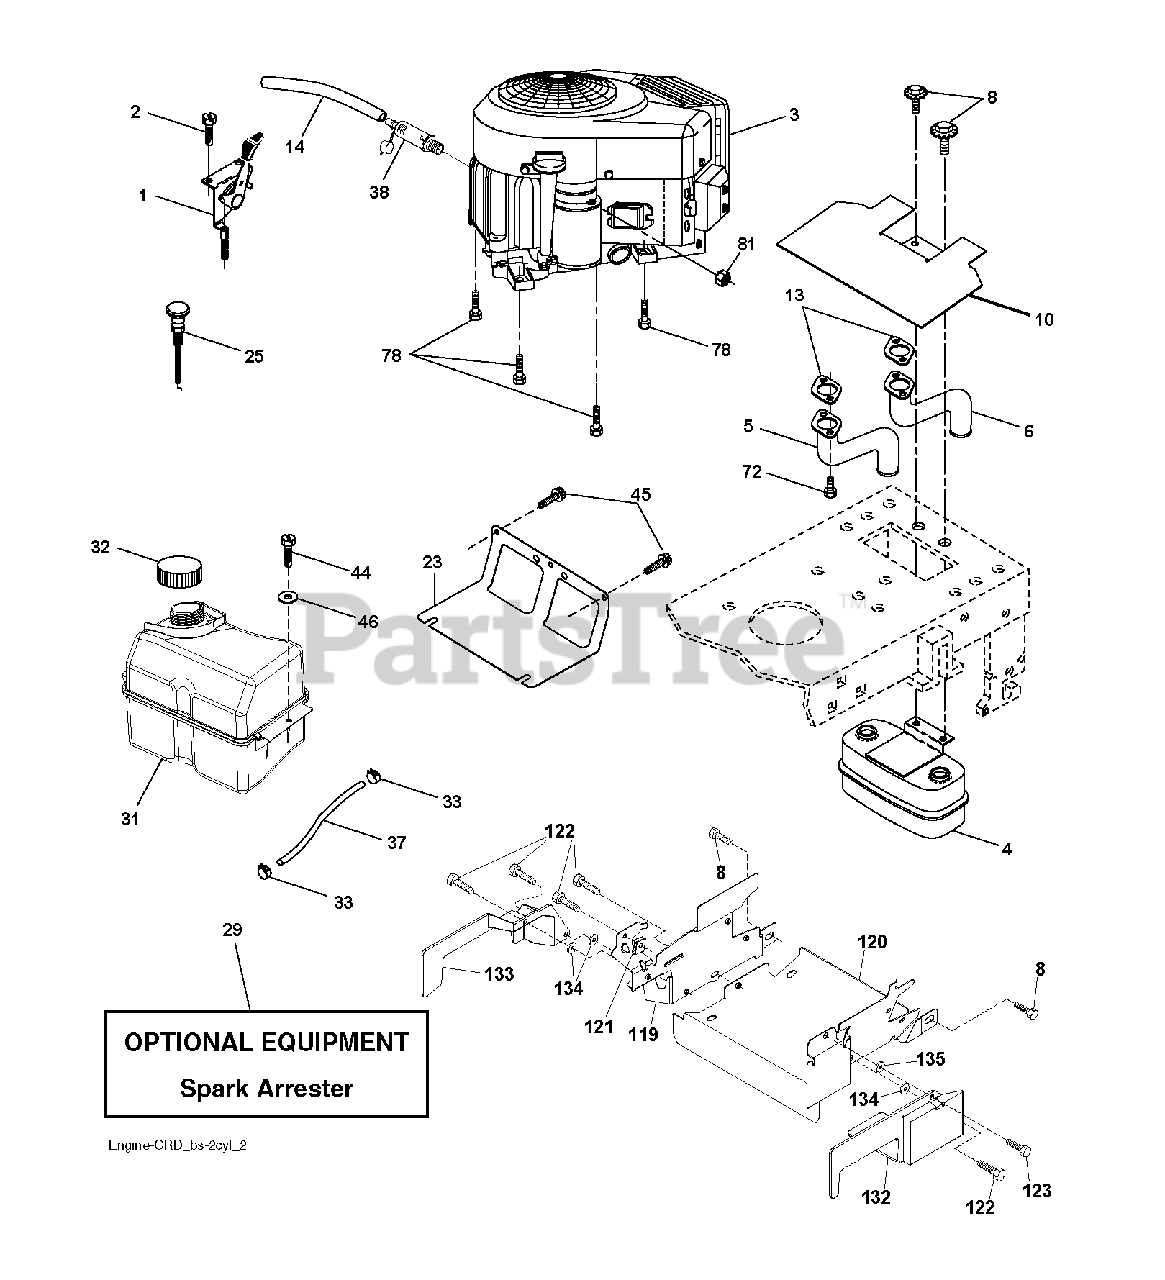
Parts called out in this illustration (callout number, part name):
1	THROTTLE CABLE
2	SCREW.#10 X 0.750.BOS THREAD
4	MUFFLER.TWIN.CYL.LOW.TONE
5	EXHAUST TUBE RH
6	TUBE MANIFOLD LH
8	BOLT, 5/16-18 X 1 3/4
10	RP SHIELD HEAT MUFFLER
13	GASKET.MUFFLER
14	TUBE, DRAIN OIL ASM.
23	SHEILD.BROWNING.DBR.GUARD
25	CONTROL CHOKE
29	ARRESTER SPARK (OPTIONAL)
32	FUEL CAP
33	HOSE CLAMP
37	LINE.FUEL.20
38	PLUG DRAIN OIL EASY
44	SCREW HEXWSHR 1/4-20X3/4
45	SCREW, 3/8-16X3/4
72	SCREW.SOCKET.HEAD.5/16-18
78	SCREW.3/8-16
81	NUT
122	SCREW.1/4-20X5/8
123	SCREW, 5/16-18 X 1/2
134	PALNUT 1/4
